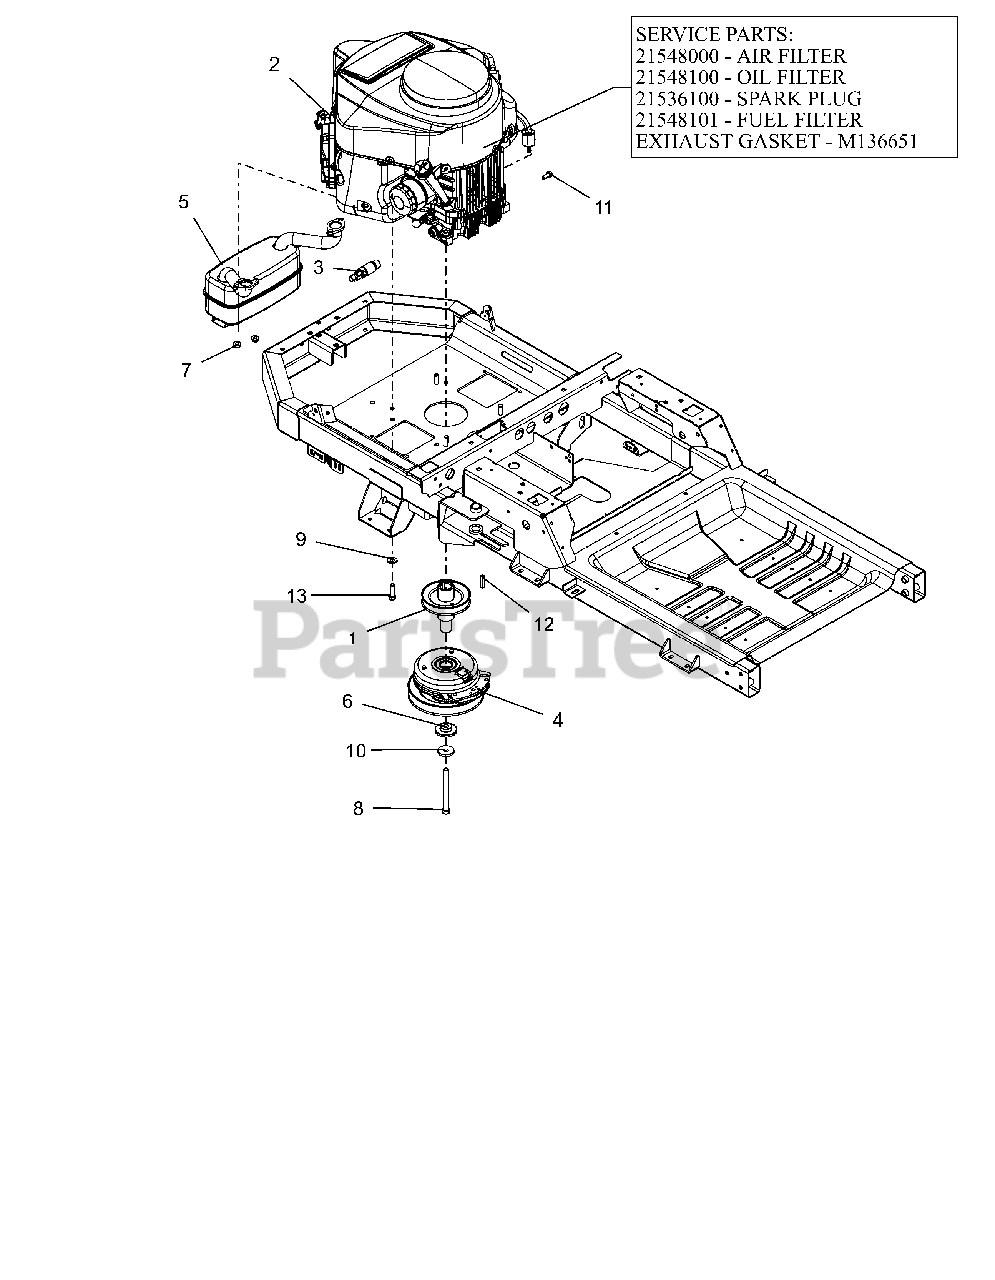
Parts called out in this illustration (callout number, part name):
1	WLDMT, DRIVE SHEAVE-X
2	ENGINE, KAWASAKI FR691 23HP
2	AIR FILTER, KAWASAKI FR
2	OIL FILTER, KAWASAKI FR
2	PLUG, SPARK
2	FUEL FILTER-KAWASAKI FR
2	GASKET, MUFFLER #
3	DRAIN, OIL M20X2.5
4	CLUTCH,105FTLB MONOPOLE 6.83"
5	MUFFLER - KAWASAKI
6	BSHG-FLG .469X1.06X.574X2.0
7	NUT-LK-TOP-FLG M8 ZCC
8	BLT, HEX .44-20X4.50 G8 ZCC NT
9	WASHER, 3/8" SPRING DISC
10	WASHER, 7/16" SPRING DISK
11	BLT, HEX M8-1.25X20 G8.8 ZCC
12	KEY-SQ .25 X 1.25 X .25 SAE
13	BLT, HEX .38-16X1.25 G5 ZCC NT
